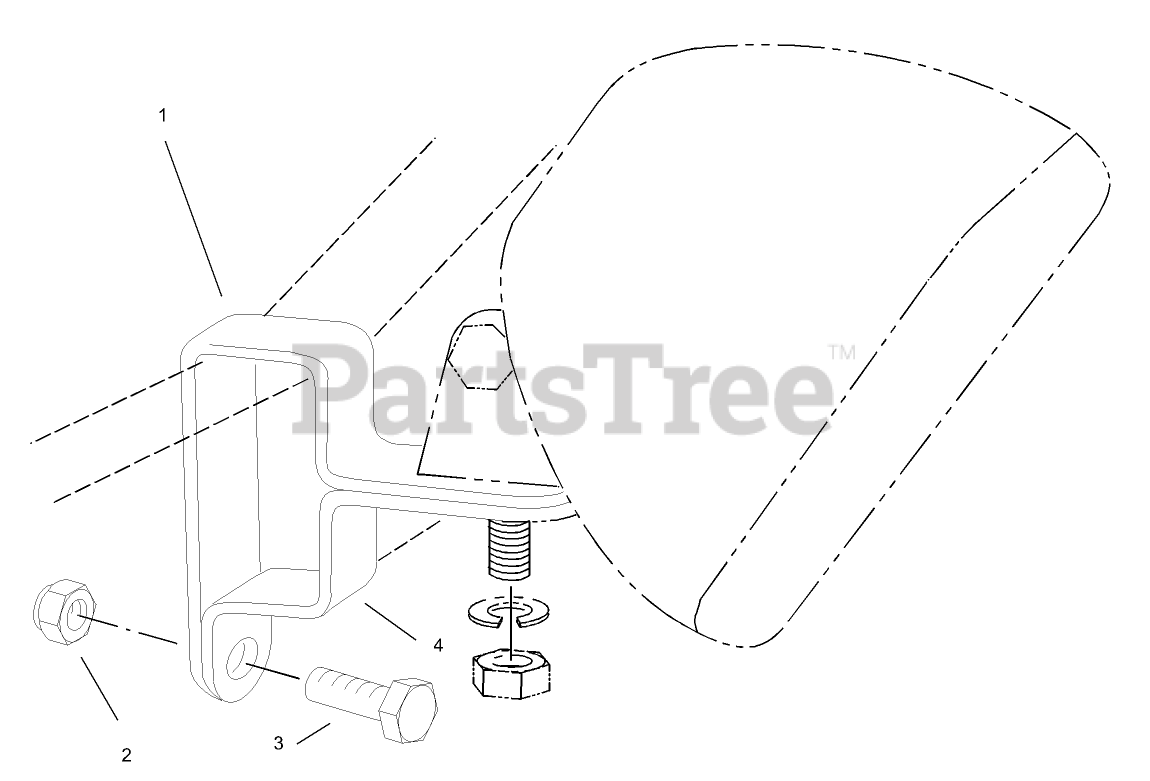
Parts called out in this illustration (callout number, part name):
1	BRACKET-LIGHT,UPPER
2	NUT-LOCK, NI
3	SCREW-HH
4	BRACKET-LIGHT,LOWER
